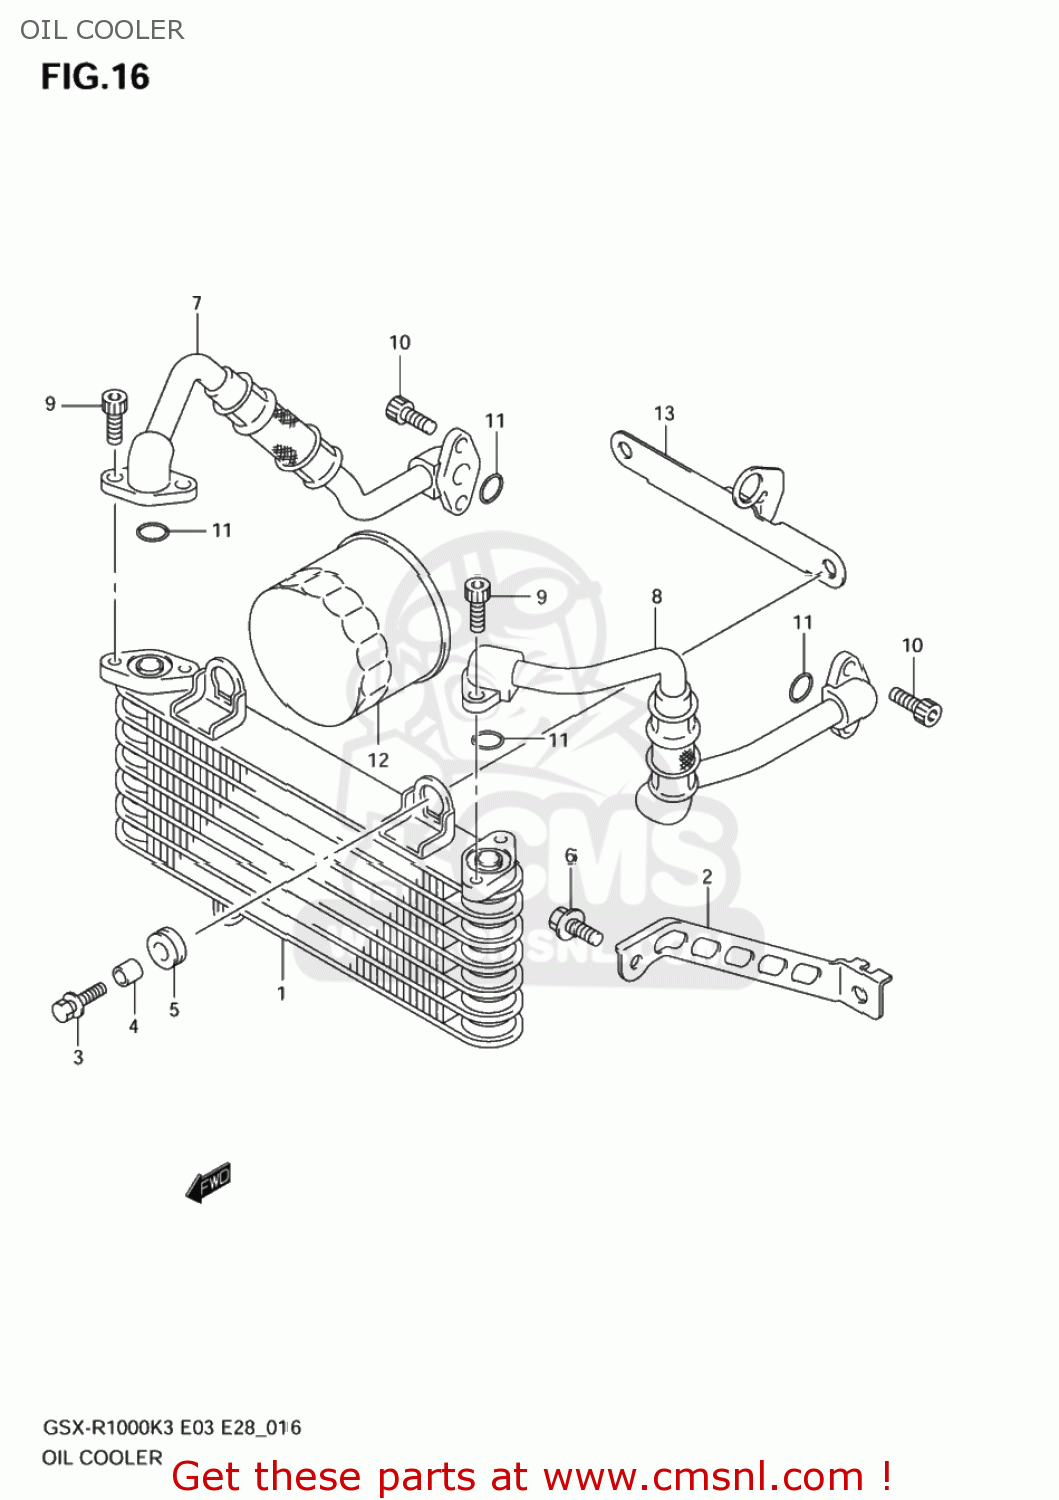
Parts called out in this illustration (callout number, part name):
1	COOLER ASSY,OIL
2	BRACKET,OIL COOLER
3	BOLT(6X25)
4	SPACER(6.5X10X10)
5	CUSHION
6	BOLT
7	HOSE,OIL COOLER,R
8	HOSE,OIL COOLER,L
9	BOLT(6X20)
10	BOLT(6X16)
11	O RING(D:2.4,ID:11.8)
12	FILTER ASSY,EN
13	BRACKET,RADIATOR SUPPORT
